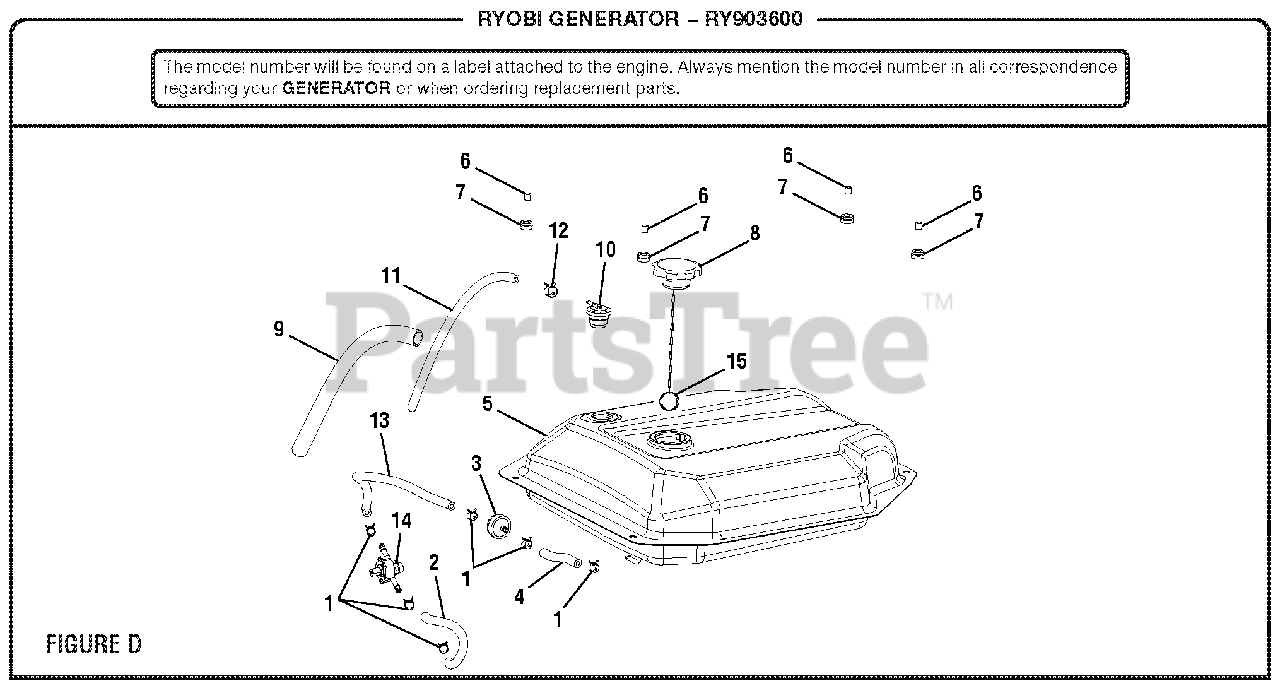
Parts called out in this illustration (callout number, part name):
1	Fuel Line Clamp (1/2 in.)
2	Fuel Hose (175 mm)
3	Fuel Filter Inline (1/4 in.)
4	Fuel Hose (80 mm)
5	Fuel Tank
9	Fuel Hose Cover (200 mm)
10	Vapor Vent
11	Vapor Hose
12	Fuel Line Clamp (7/16 in.)
13	Fuel Hose (300 mm)
14	Fuel Valve
15	Ring Clip
